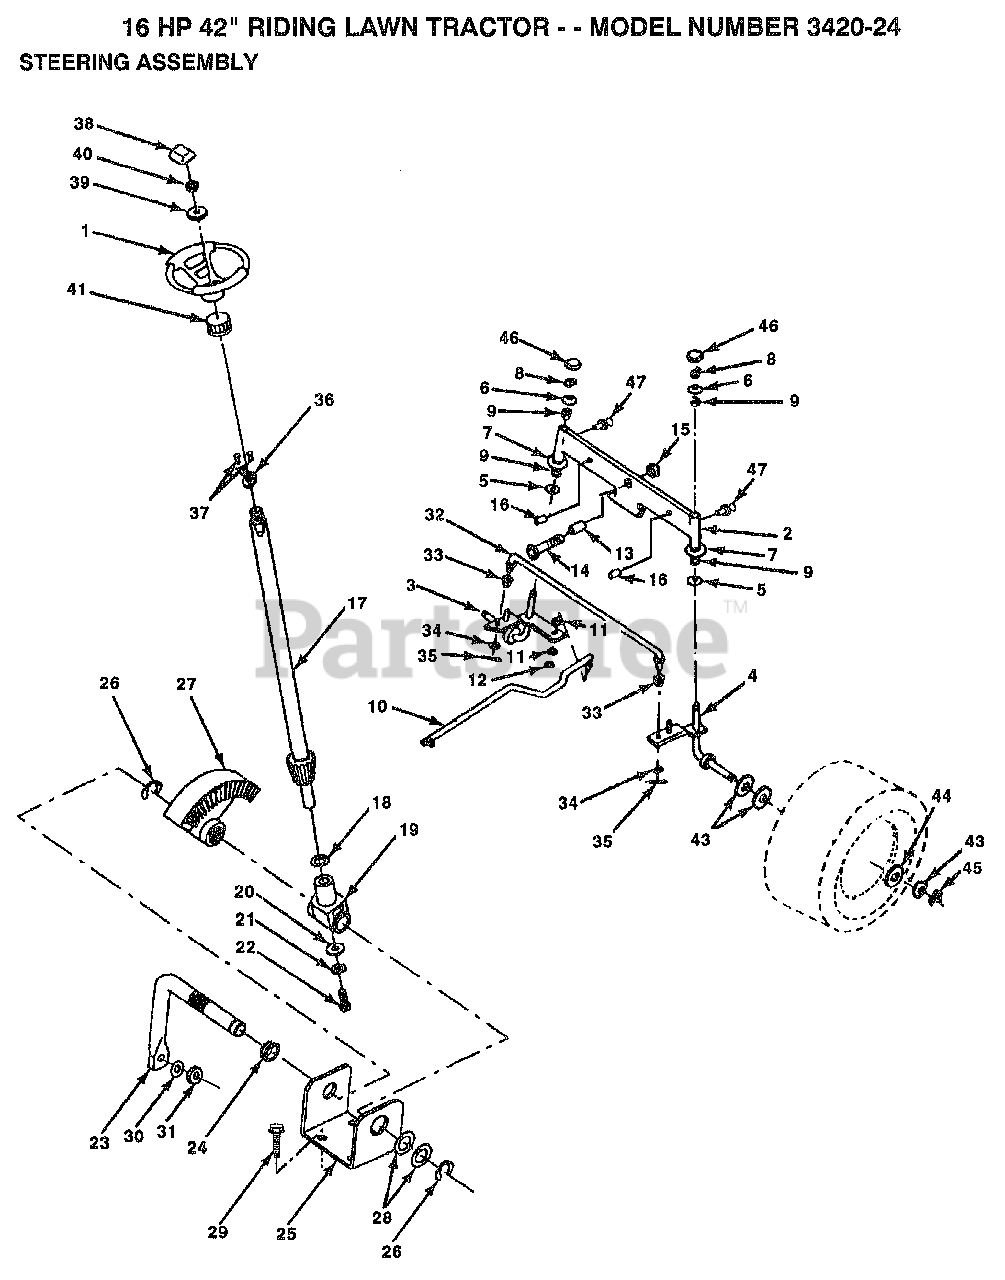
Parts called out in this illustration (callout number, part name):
3	SPINDLE LH
4	SPINDLE RH
5	WASHER .T
6	WASHER
7	WASHER
8	RING
9	COL. SRTG. BEAR.
11	LOCKWASHER
13	BEARING
14	BOLT HEX 5/8-11
16	AXLE PIN
17	STEERING SHAFT
18	THRUST WASHER
19	SUPPORT.SHAFT
21	LOCKWASHER
22	"SCREW,SPECIAL"
24	NYLINER T
25	"BRKT,STEERING"
26	RING
28	WASHER .T
29	SCREW
30	LOCKWASHER
32	TIE ROD
33	BUSHING.DRAGLINK
34	WASHER
35	COTTER PIN
38	ST WHL INSERT CAP
39	WASHER
41	ADAPTER LT
43	WASHER
44	WASHER
45	RING
46	CAP
47	ZERK M
